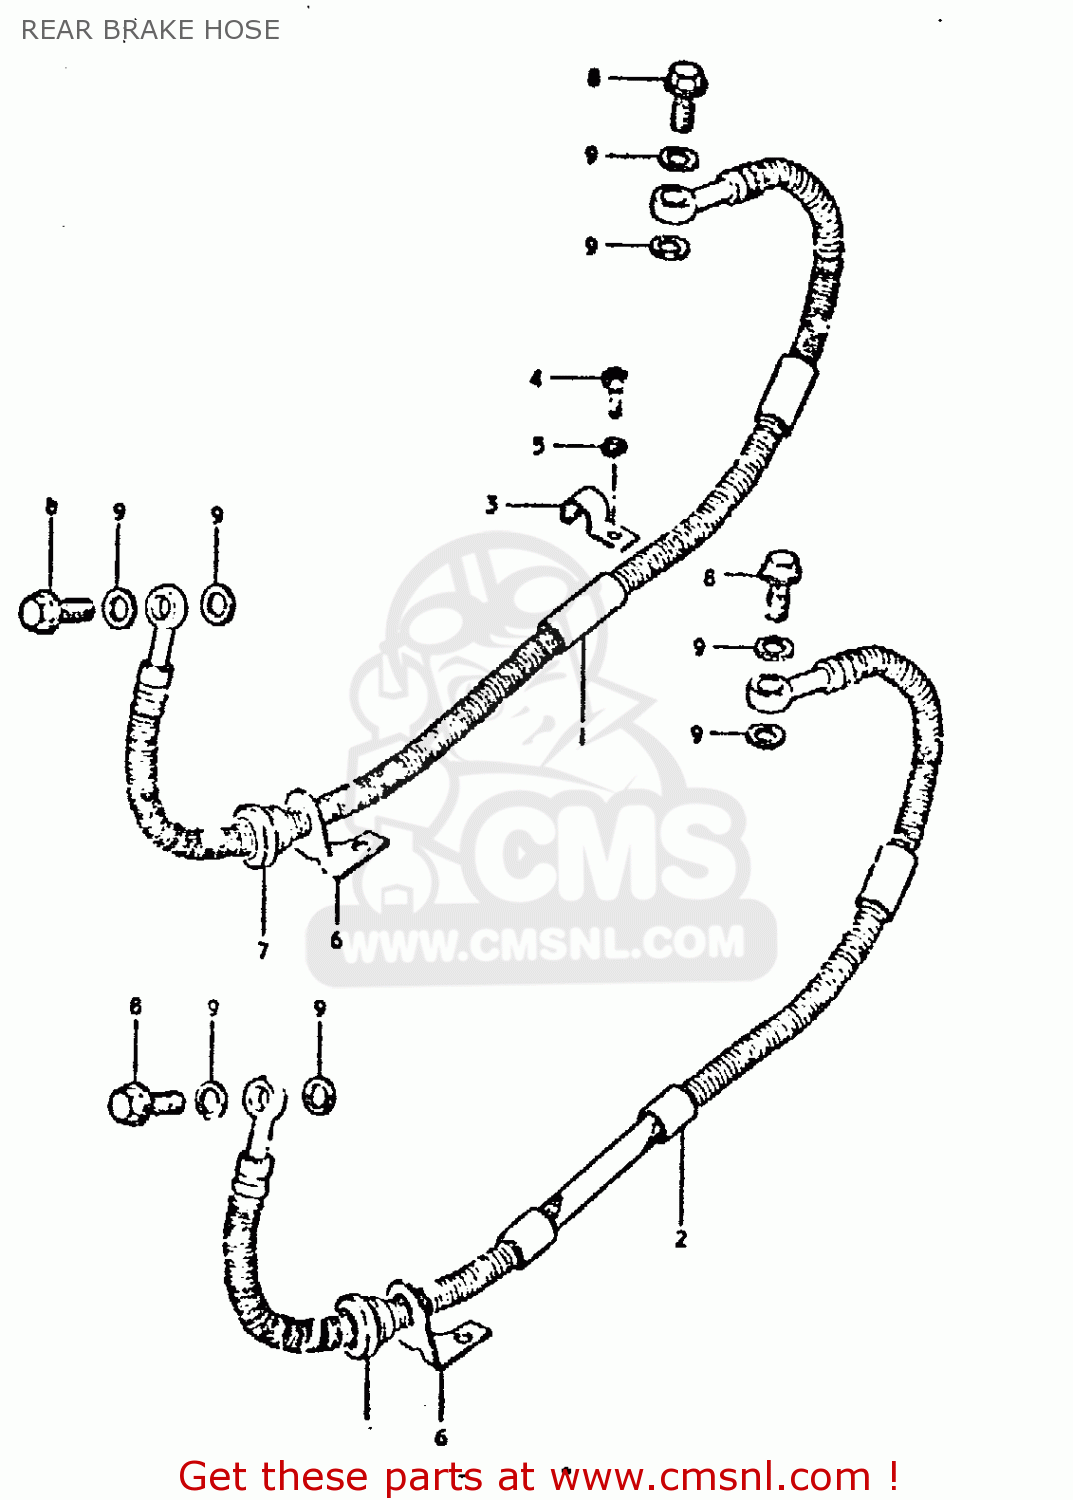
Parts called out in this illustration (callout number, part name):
1	HOSE,REAR BRAKE
2	HOSE,REAR BRAKE
3	CLAMP,REAR BRAKE HOSE
4	SCREW(6X8)
5	LOCK WASHER
6	GUIDE,BRAKE HOSE
7	GROMMET,BRAKE HOSE GUIDE
8	BOLT,UNION
9	WASHER
